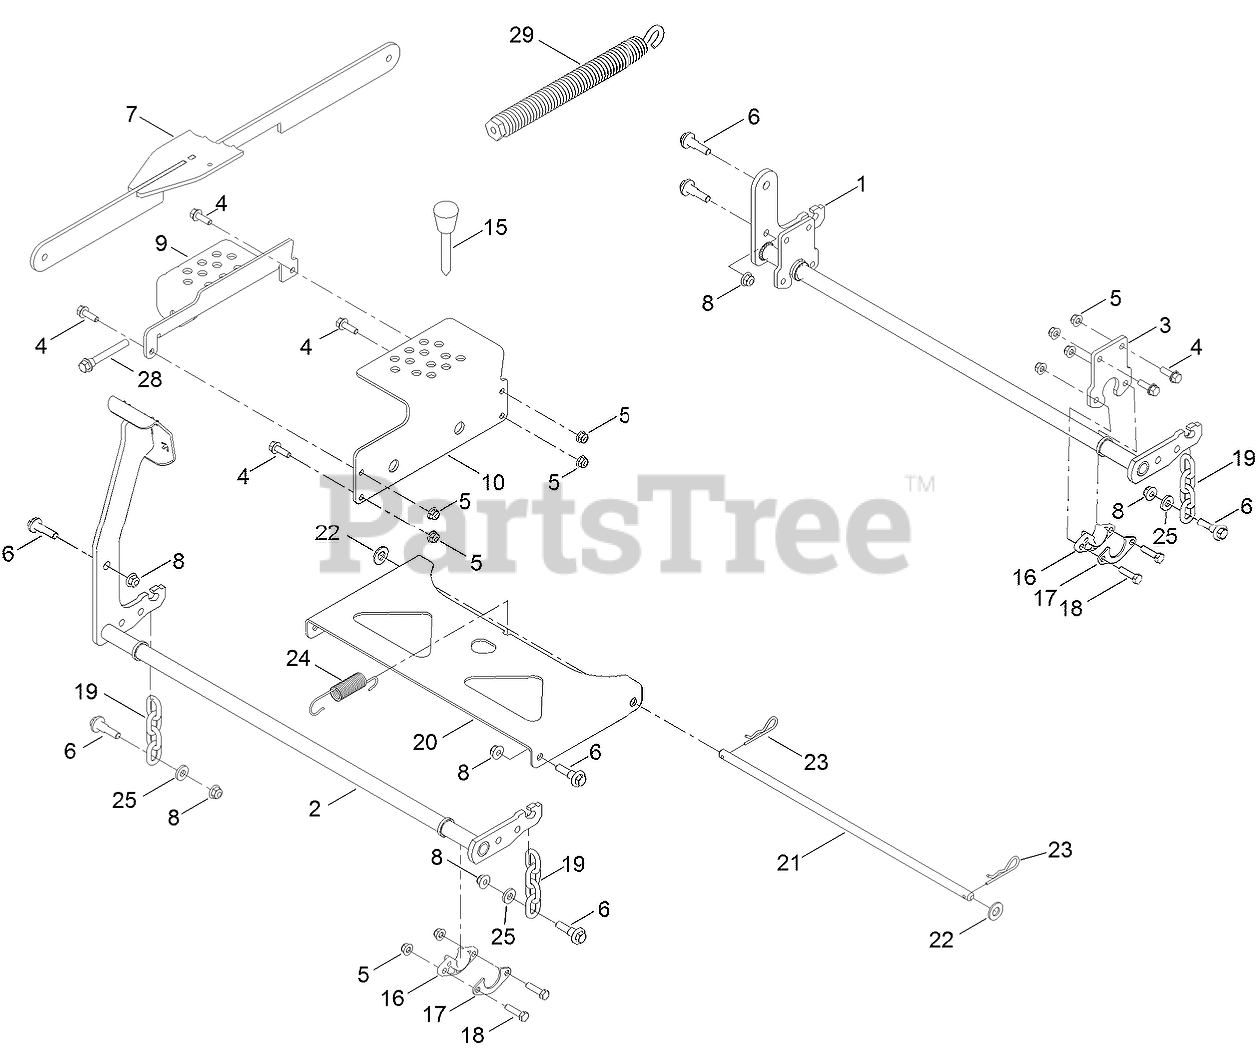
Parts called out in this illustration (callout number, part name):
1	PIVOT-REAR
2	PIVOT-FRONT
4	SCREW-HHF
5	NUT-HF, NI
6	BOLT-SHOULDER
7	LIFT LINK ASM
8	NUT-HF, NI
9	PLATE-HOC, LOWER
10	PLATE-HOC, UPPER
15	HOC PIN ASM
16	BEARING-FLANGE
17	GUSSET-DECK LIFT
18	SCREW-HH
19	CHAIN-DECKLIFT, 4-LINK
20	PAN-PIVOT, DECK
21	ROD-PIVOT, DECK
22	WASHER-FLAT
23	PIN-COTTER
24	SPRING-EXTENSION
25	SPACER-HUB, BLOWER
28	BOLT-SHOULDER
29	SPRING-EXTENSION
